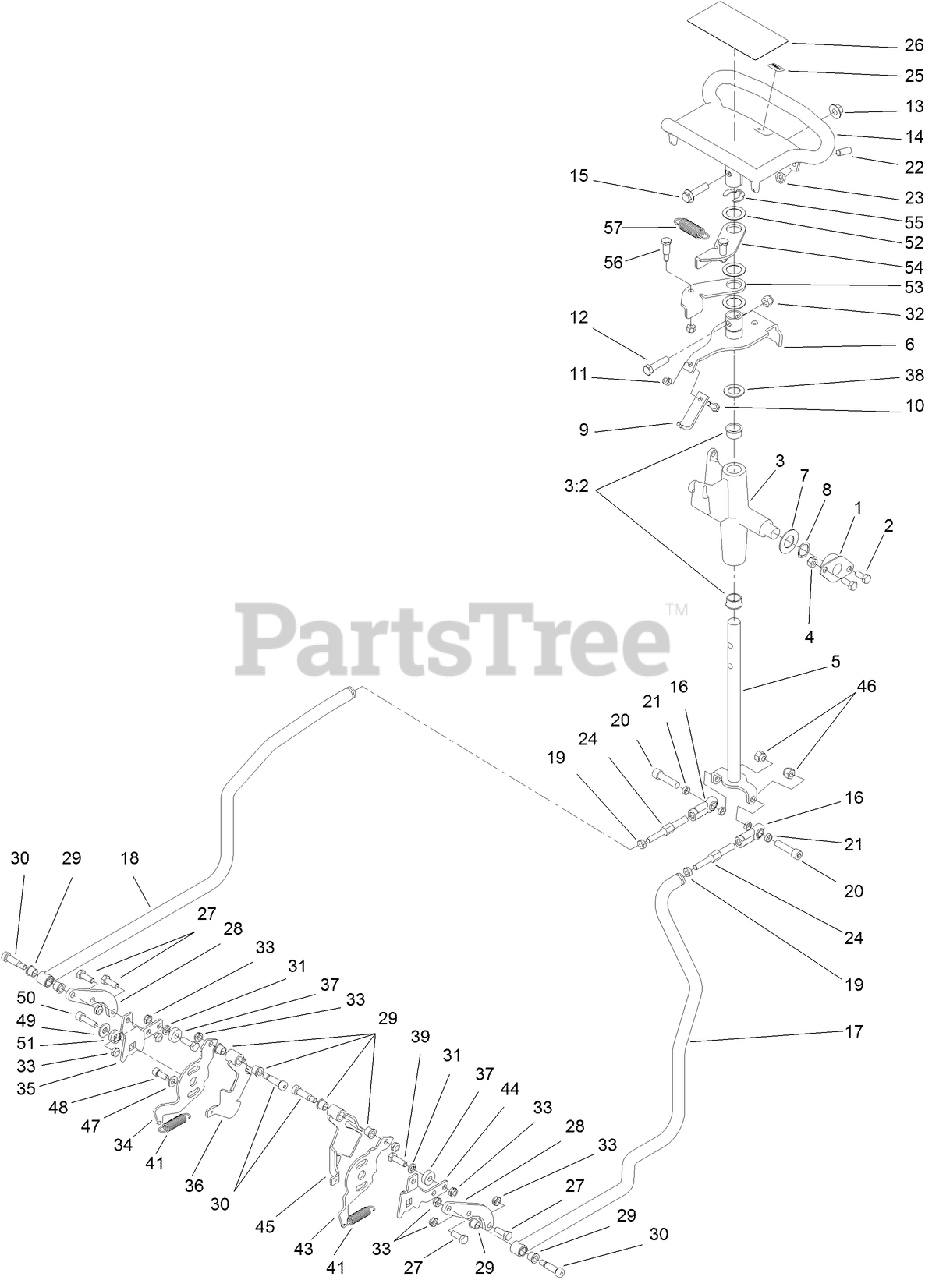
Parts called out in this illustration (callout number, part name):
1	BUSHING
2	SCREW-HH
3	CONTROL SUPPORT ASM
3:2	BEARING-FLANGE
4	NUT-LOCK, NI
5	ROD-DRIVE
6	LEVER-PIVOT
7	WASHER-FLAT
8	WASHER-SPRING, WAVE
9	PLATE-NEUTRAL
10	SCREW-HH
11	NUT-LOCK, NI
12	SCREW-HH
13	NUT-FLANGE
14	HANDLE-CONTROL
15	SCREW-HHF
16	JOINT-BALL END, LH
17	ROD-CONTROL,
18	ROD-CONTROL, RH
19	NUT-JAM
20	SCREW-HSH
21	SPACER-PLATE, RETAINING
22	SCREW-SET
23	NUT-JAM
24	LINK-CONTROL, ADJUSTMENT
25	DECAL
26	DECAL-TRACTION
27	SCREW-HH
28	PLATE-ADAPTER, CONTROL, RH
29	BUSHING-FLANGE
30	BOLT-SHOULDER
31	WASHER-LOCK
32	NUT-LOCK, NI
33	NUT-LOCK, NI
34	PLATE-BASE, RH
35	PLATE-ARM, RETURN
36	PIVOT-RH
37	BEARING-BALL
38	WASHER-THRUST
39	SCREW-HH
41	SPRING-EXTENSION
43	PLATE-BASE, LH
44	PLATE-ARM, RETURN, LH
45	PIVOT-LH
46	NUT-LOCK, NI
47	WASHER-BELLEVILLE
48	SCREW-HSH
49	WASHER-FLAT
50	SCREW-HSH
51	LOCK-TRUNION
52	WASHER-PLAIN
53	LEVER-RETURN, RH
54	LEVER-RETURN, LH
55	RING-RETAINING
56	SCREW-SHOULDER
57	SPRING-EXTENSION
